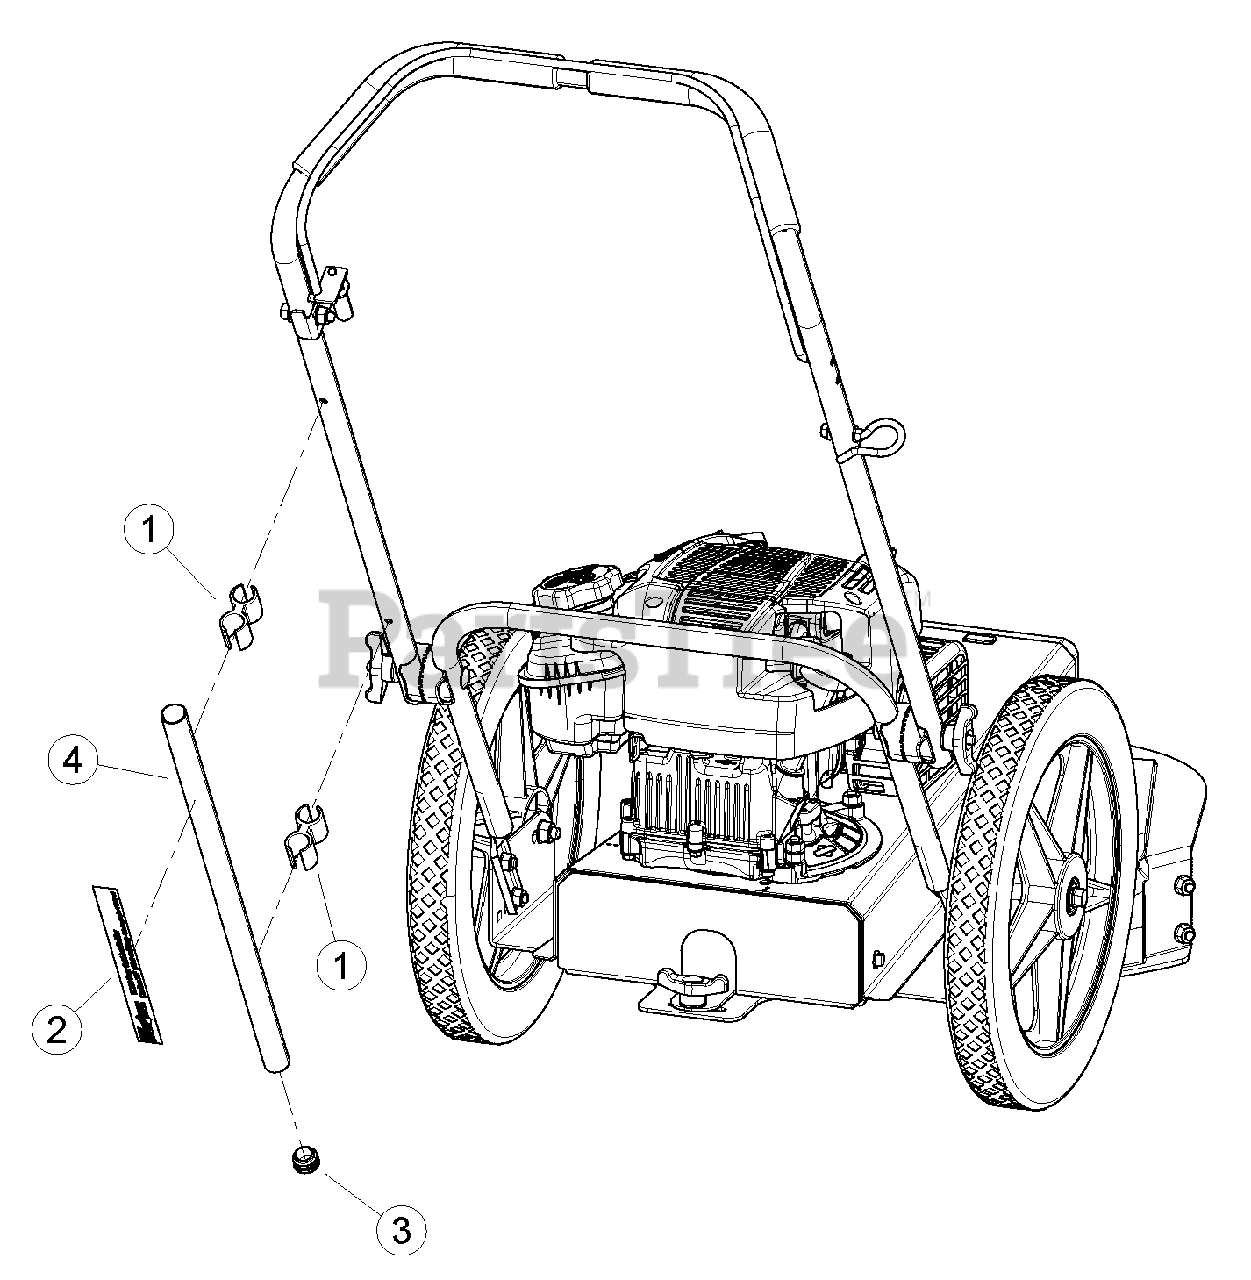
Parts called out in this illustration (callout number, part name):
1	CLIP, LINE TUBE
2	DECAL, TRIMMER LINE HOLDER
3	PLUG, LINE HOLDER TUBE
4	TUBE, TRIMMER LINE HOLDER
